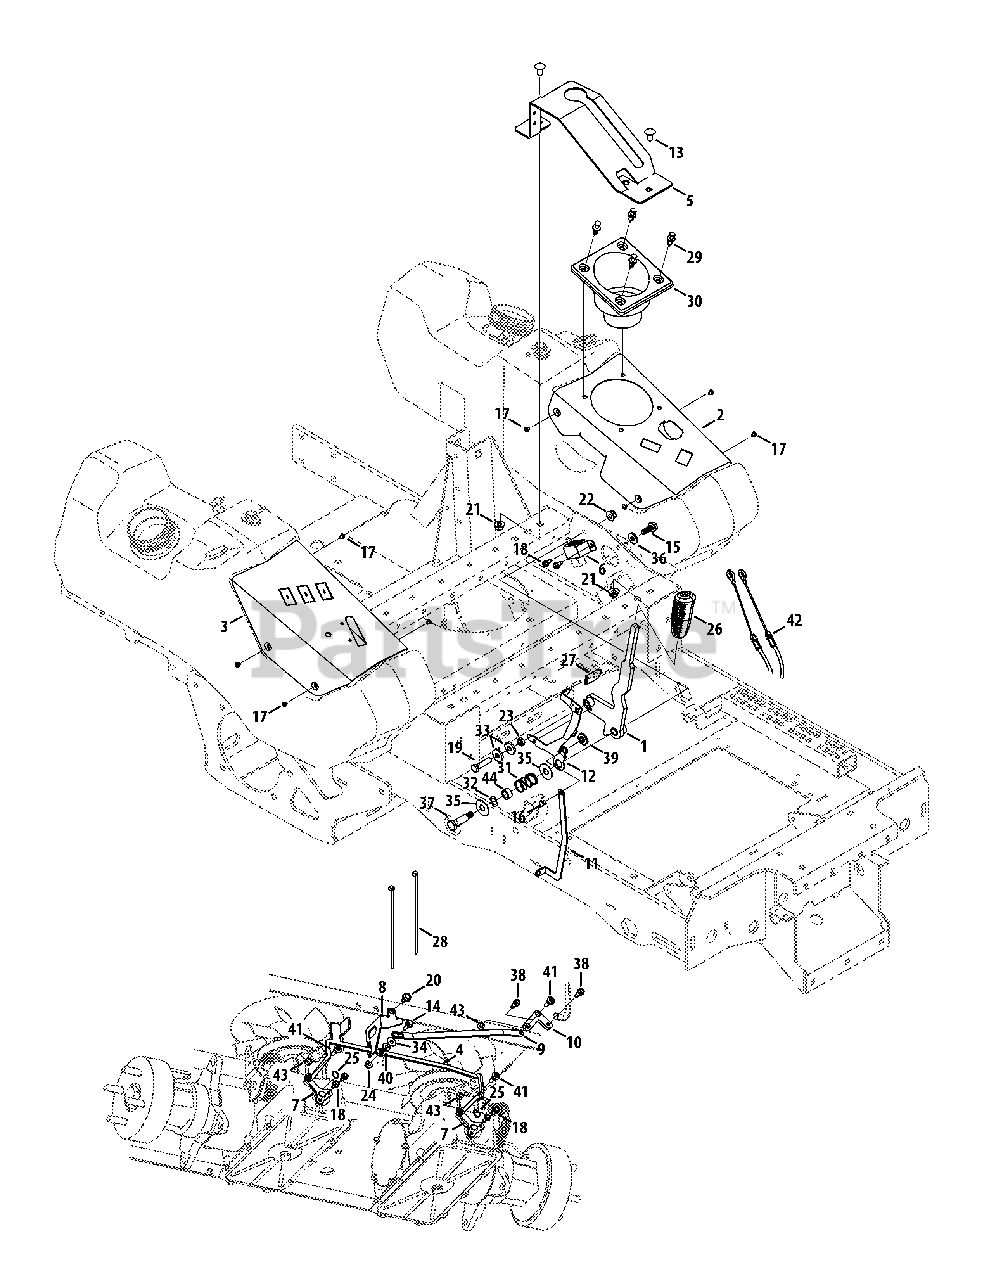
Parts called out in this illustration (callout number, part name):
1	Brake Handle Assembly
2	LH Control Panel
3	RH Control Panel
4	Dump Valve Actuator Bracket
5	Boot Brake Bracket
6	Brake Switch Mount
7	Transmission Bypass Lever
8	Neutral Switch Bracket
9	Transmission Actuator Arm
10	Neutral Pivot Control Lever
11	Neutral Arm
12	Dump Valve Release Lever
13	Carriage Bolt, 3/8-16 x .75
14	Hex Flange Screw, 1/4-20 x .75
15	Screw, 3/8-16 x 1.00
16	Screw, M6 x 8mm
17	Machine Screw, #10-32 x .25
18	Hex Flange Screw, 1/4-20 x .500
19	Hex Cap Screw, 3/8-16 x 1.50
20	Screw, 5/16-18 x .50
21	Nut, 3/8-16, Flangelock
22	Nut, 3/8-16, Flangelock
23	Jam Nut, 3/8-16
24	Nut, 1/4-20, Hexflange
25	Retainer Ring
26	Grip, .50 ID
27	Grip, Seat, Adjustment (Yellow)
28	Cable Tie
29	Rivet, .3125
30	Cup Holder
31	Compression Spring, .844 x .97 x 1.5
32	Washer, Wave, .531 x .781 x .013
33	Flat Washer, .385 x 1.00 x .135
34	Flat Washer, .283 x .750 x .030
35	Flat Washer, .508 x 1.325 x .040
36	Flat Washer, .406 x .875 x .105
37	Shoulder Screw, .498 x 1.445
38	Shoulder Screw, .342 x .335, 1/4-28
39	Shoulder Spacer, M6
40	Shoulder Spacer, .375 x .625 x .20
41	Shoulder Screw, .375 x .280, 1/4-14
42	Brake Cable
43	Spacer, .256 x .500 x .240
44	Spacer, .51 x .75 x .390
